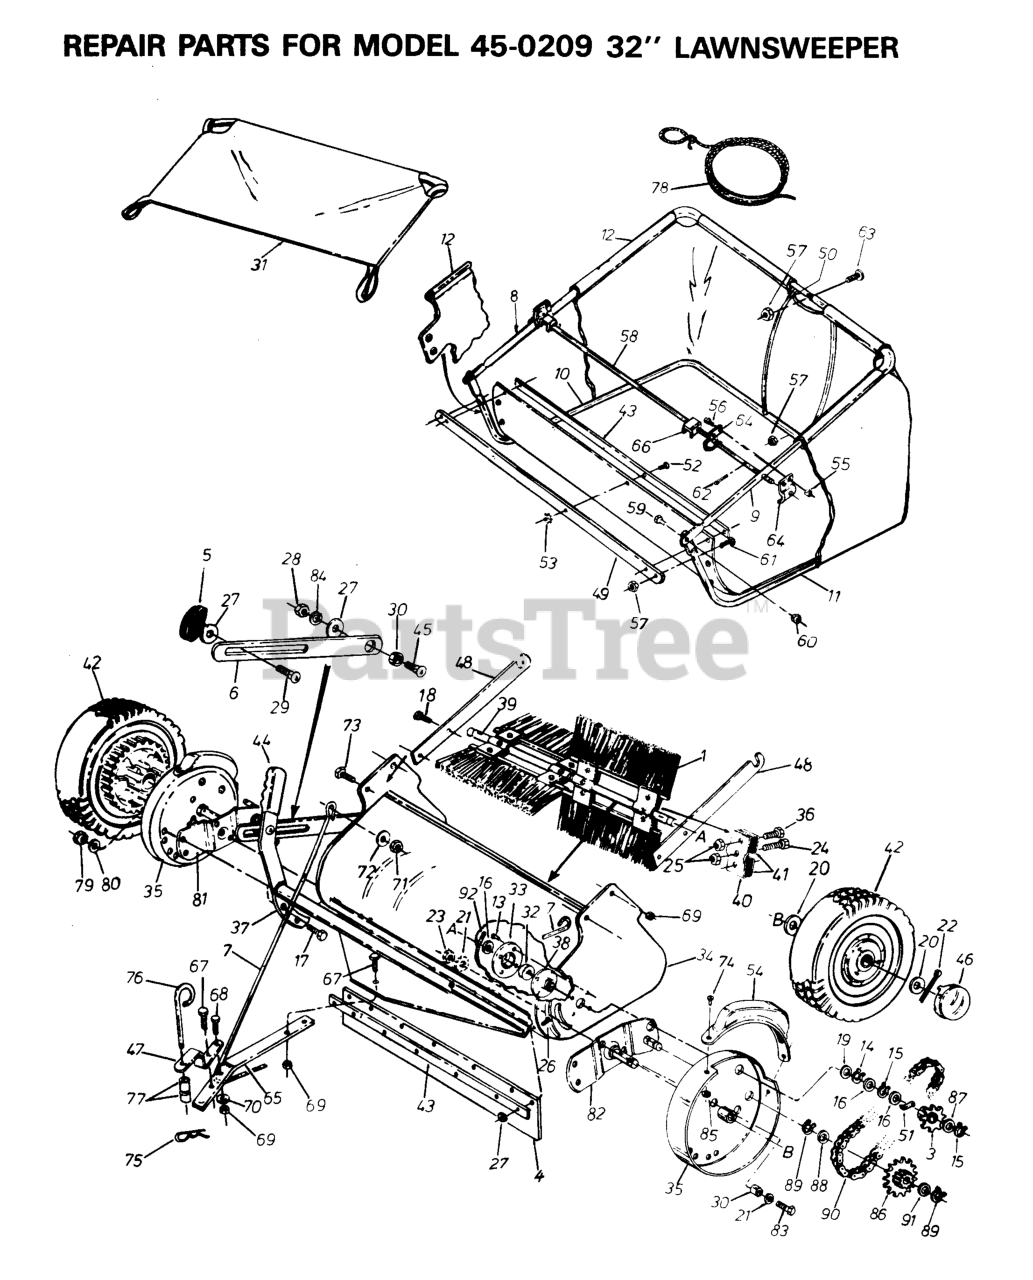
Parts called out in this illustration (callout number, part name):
3	RATCHET SPROCKET
5	Knob, Wing 5/16-18 Thread
6	HEIGHT ADJUSTMENT STRAP
12	REPL BY 531 00 28-55
14	Ring, Retaining 3/4"
15	Retaining Ring .594" I.D.
16	SHIM WASHER
17	BOLT.FIN.HEX.5/16-18X3/4
18	HEX BOLT
19	Washer, Flat 1-1/8" x .78" x .025"
20	Washer, 1/2" x 1" x .02"
21	WASHER
23	HEX LOCK NUT 3/8-24THD
27	WASHER BRB 8.4X17
30	Spacer 13/32" x 5/8" x 3/16"
31	REPL BY 531 00 28-56
32	BALLBEARING 5916 1.D
33	BEARING RETAINER
35	DUST PROTECTION
36	REPL BY 725 23 74-71
38	BRUSH BUSHING ASSY
40	BRUSHRETAINER DOUBLE
41	BRUSH RETAINER SINGLE
44	Rubber Grip
45	RP BOLT 5/16-18 X3/4 ZN/YEL GR
47	HITCH BRACKET
48	HOPPER MOUNT ARM
50	HOPPER SUPPORT ROD
52	Slotted Truss Head Screw #10-32 x 5/8"
53	LOCKNUT M5
56	BOLT.FIN.HEX.5/16-18X3/4
59	HEX BOLT
61	SCREW M6S 6X30
63	Curved Head Bolt 1/4-20 x 1"
64	HOPPER MOUNTING CLAMPS
66	BAG RETAINER CLEVIS
68	BOLT
70	Washer, Flat 1-1/2" x .375" x .062"
72	WASHER
73	HEX BOLT
76	Pin, Hitch
77	Hitch Adjustment Tube
80	WASHER - M6
88	Washer, 1/2" x 1" x .02"
89	RETAINING RING 1/2Ä
